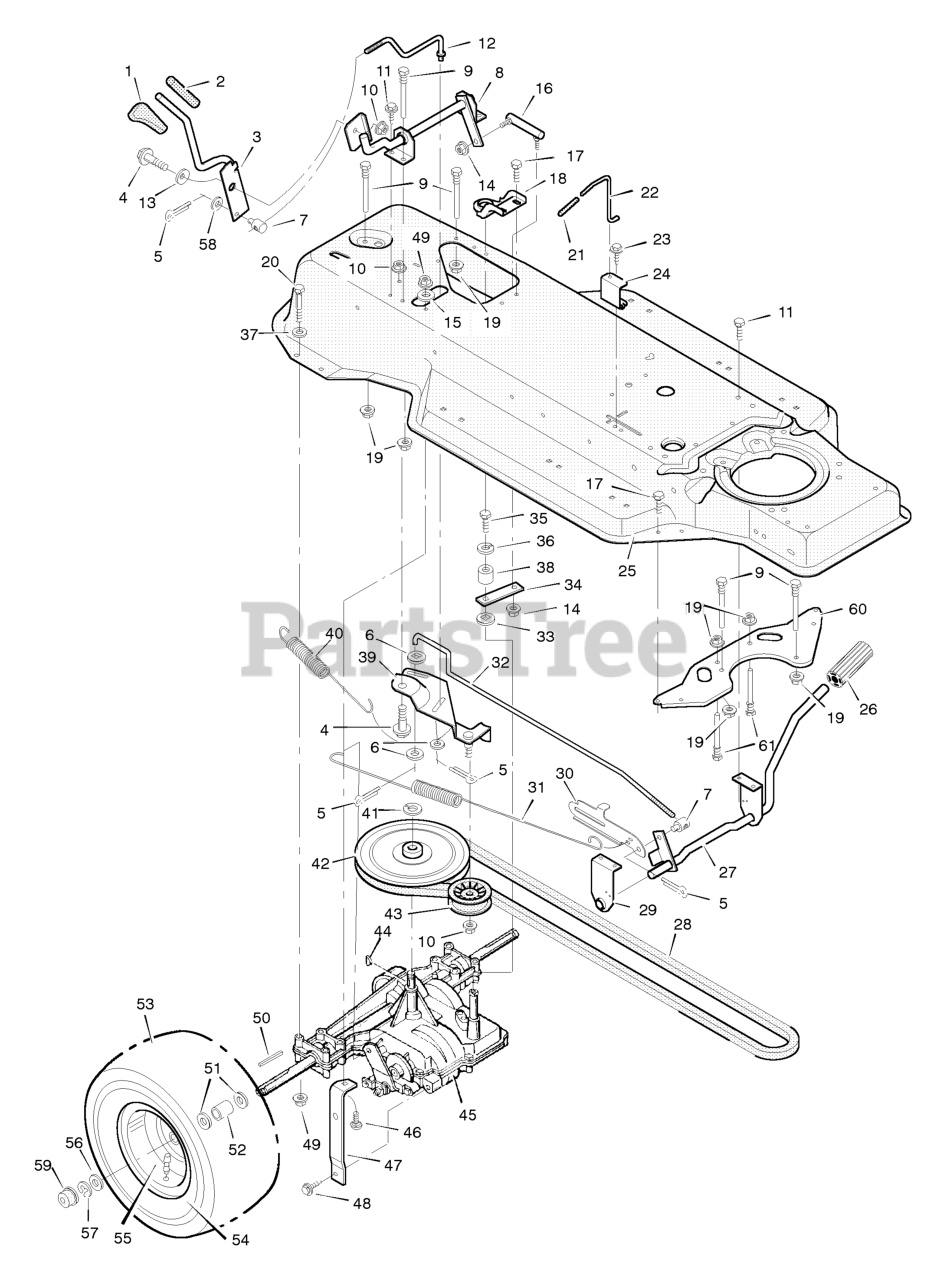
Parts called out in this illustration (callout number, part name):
1	Grip
3	Handle, Shift
4	Bolt, Shoulder
5	Pin, Cotter
6	Washer
7	Nut, Adjustable
8	Shifter Assembly
9	Guide, Belt
10	Locknut, Flange
12	Link, Clutch
13	Washer, Curved
14	Locknut, Flange
16	Link Assembly, Shifter
18	Bracket, Support
19	Nut, Flange
20	Bolt, Hex
22	Rod, Control
24	Guide, Bracket
25	Frame Assembly
26	Pedal, Clutch/Brake
27	Lever Assembly
28	Belt, Motion Drive
29	Bracket, Lever Support
30	Latch, Park Brake
31	Spring, Brake Extension
32	Rod, Clutch
34	Yoke, Shift
35	Bolt, Hex
36	Lockwasher
37	Washer
38	Pilot, Support
39	Bracket Assembly, Idler
40	Spring, Motion Drive
41	Ring, Retainer
42	Pulley, Motion Drive
43	Pulley, Backside Idler
44	Key, Woodruff
45	Transaxle, Peerless **
46	Bolt, Carriage
47	Support, Transaxle
49	Locknut, Flange
50	Key, Square
52	Spacer, Transaxle
53	Tire *
54	Wheel and Tire Assembly
55	Valve Stem
57	E- Ring
58	Washer
59	Hub Cap
60	Plate, Belt Guide
61	Guide, Belt
